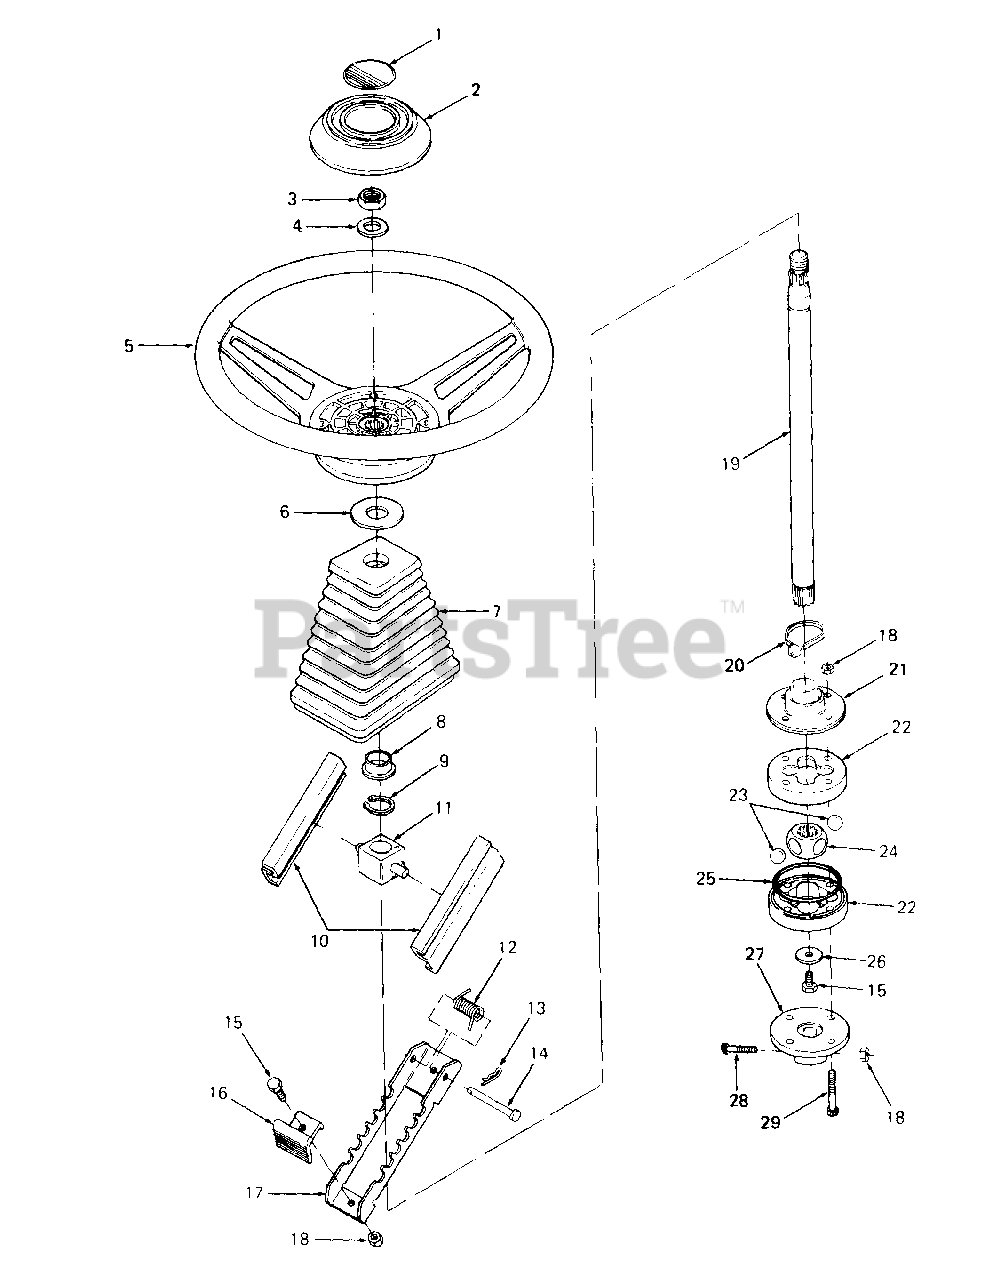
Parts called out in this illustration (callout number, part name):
1	Label, Steering Cap
2	Cap, Steering Wheel
3	Nut, Hex Jam, 5/8-18
4	Washer, Flat, .640 x 1.24 x .06 Thk HDN
5	Wheel, Steering
6	Washer, Flat, .758 x 2.0 x .030 Thk
7	Boot, Steering Shaft
8	Bearing, Flange
9	Ring, Snap
11	Bushing, Shaft Guide
12	Spring-Tilt, Torsion
13	Pin, Internal Cotter
14	Pin, Clevis, .25 Dia x 2.38 Lg
15	Screw, Hex Cap, 1/4-20 x .50 Lg GR5
16	Button, Tilt Control
17	Plate, Tilt Control
18	Nut, Hex Patch Lock, 1/4-20
19	Shaft, Upper Steering, 16.75 Lg
20	Strap, Tie
21	Boot, Coupling
22	Coupling, Drive w/0-Ring Groove
23	Ball, Steel, 5/8 Dia Chrome
24	Hub, Drive
25	O-Ring, 2.489 x .070
26	Washer, Flat, .265 x 1.0 x .030 Thk HDN
27	Adapter, Steering
28	Screw, Socket Hd Cap, 1/4-20 x 1.12 Lg
29	Screw, Socket Hd Cap, 1/4-20 x 1.75 Lg
